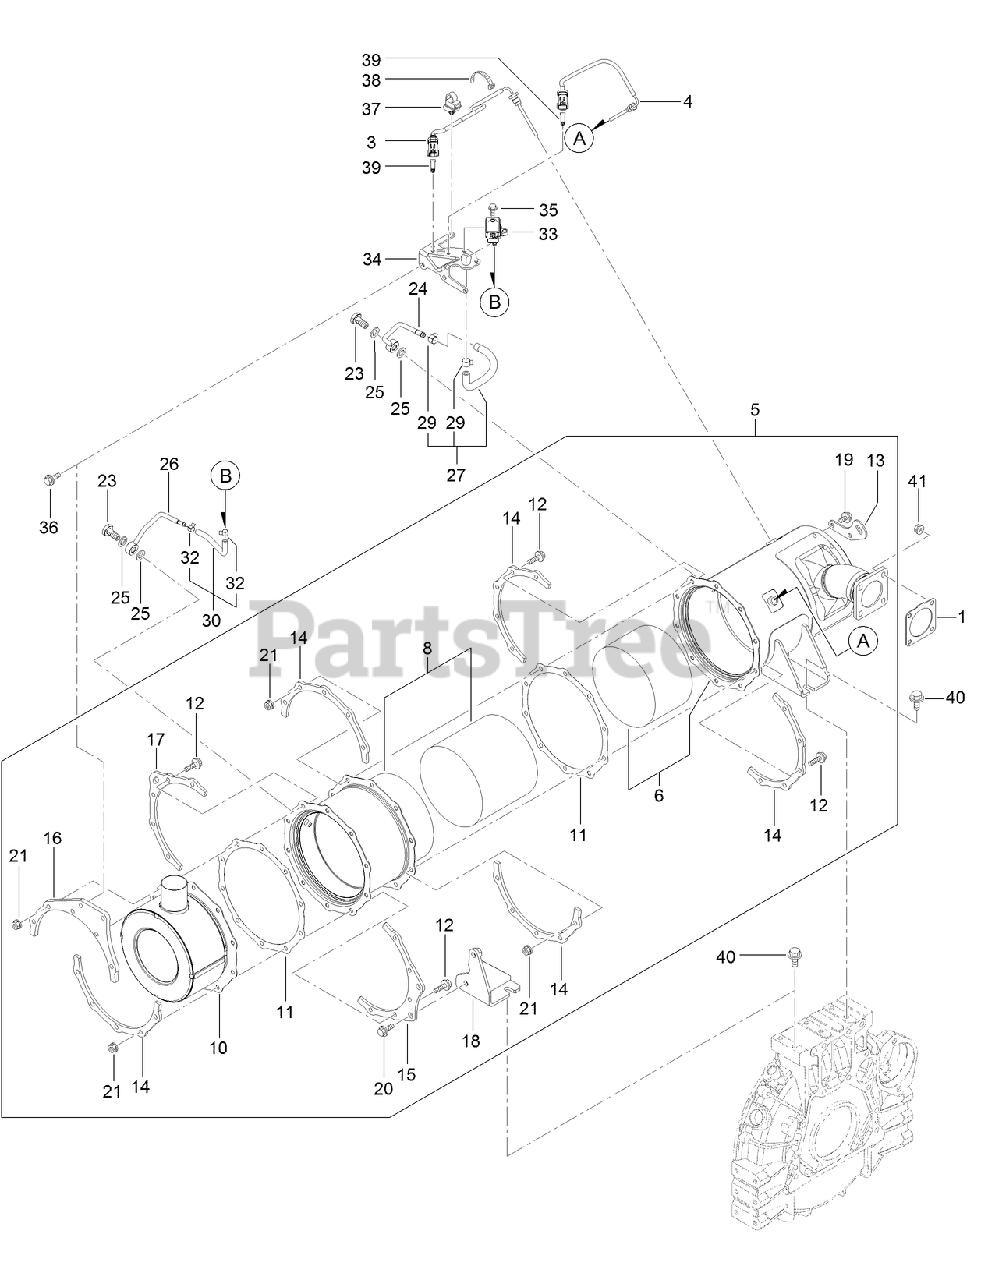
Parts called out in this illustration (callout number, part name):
1	GASKET
3	SENSOR-TEMP, EXHAUST
4	SENSOR-TEMP, EXHAUST
5	D P F ASM
6	CASE-D O C
8	CASE-FILTER, SOOT
10	DPF SILENCER
11	GASKET-D P F
13	LIFTER-D P F
14	STIFFENER-D P F, A
15	STIFFENER-D P F, B
16	STIFFENER-D P F, C
17	STIFFENER-D P F, C
18	STAY-D P F
23	BOLT-JOINT, PIPE
24	EXHAUST PRESSURE PIPE ASM
25	GASKET-SENSOR
26	EXHAUST PRESSURE PIPE ASM
27	EXHAUST HOSE ASM
29	CLIP-HOSE
30	EXHAUST PRESSURE HOSE ASM
32	CLIP-HOSE
33	SENSOR-PRESSURE
34	BRACKET-SENSOR, PRESSURE
37	BAND-CLIP
39	CLIP-CONNNECTOR
